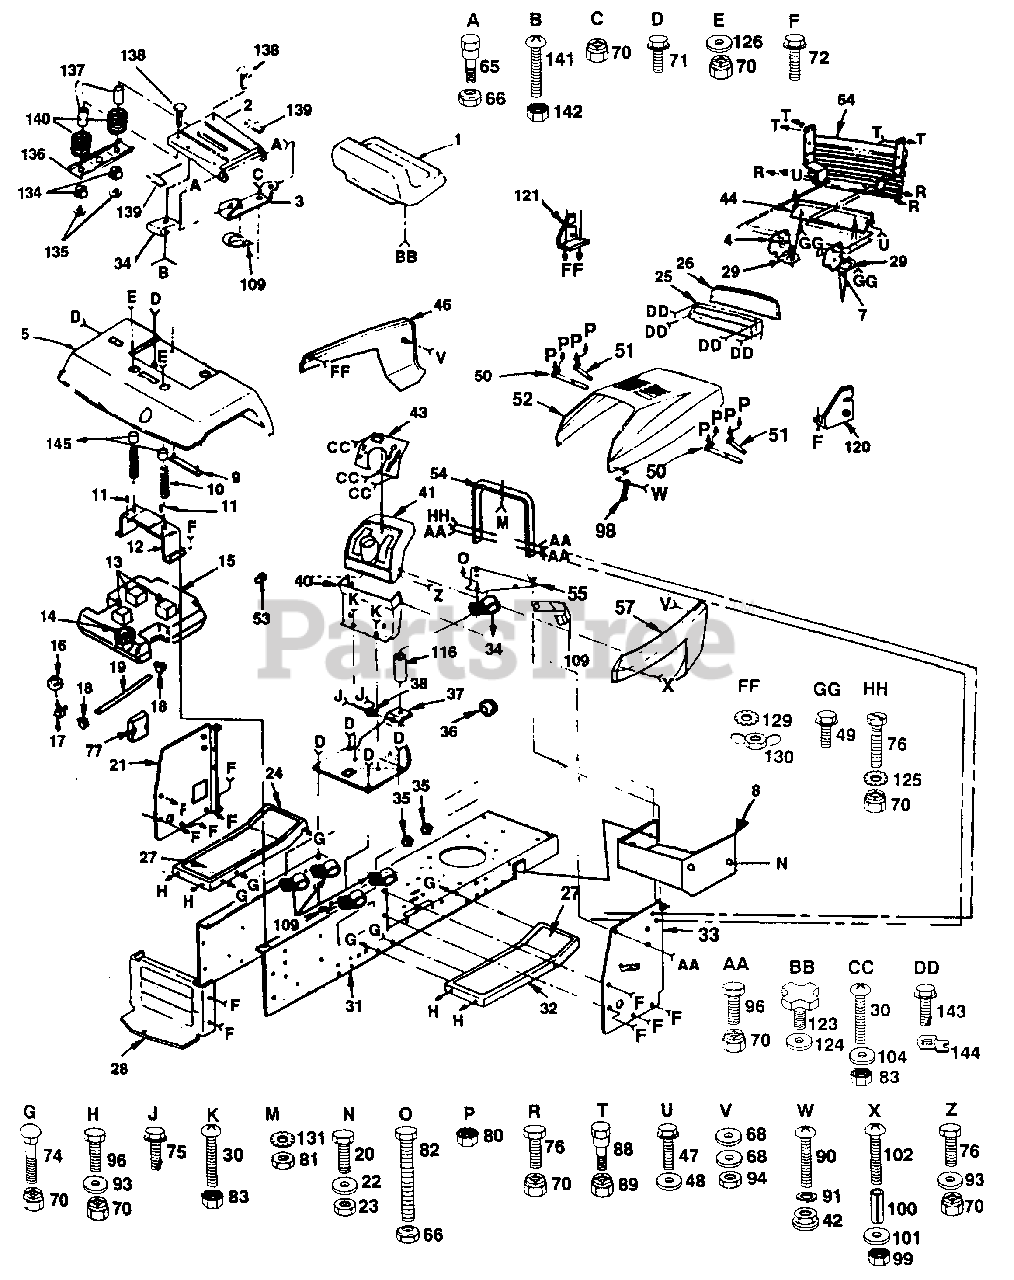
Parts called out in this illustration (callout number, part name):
1	Seat (AYP part number)
2	Pan, Seat (AYP part number)
3	Bracket, Pivot, Seat (AYP part number)
4	Bracket, Asm. L.H. Pivot (AYP part number)
5	Fender (AYP part number)
7	Bracket, Asm. R.H. Pivot (AYP part number)
8	Shield, Heat Front (AYP part number)
9	Strap, Fender (AYP part number)
10	Spring, Compression.Seat (AYP part number)
11	Nut, Push (AYP part number)
12	Bracket, Fender (AYP part number)
13	Pad, Spacer (AYP part number)
14	Cap, Fuel (AYP part number)
15	Tank, Fuel (AYP part number)
16	Bushing (AYP part number)
17	Stem, Tank, Fuel (AYP part number)
18	Clamp, Hose (AYP part number)
19	Line, Fuel (AYP part number)
20	Bolt, Hex Hd. 1/4-20 UNC X 3/4 (AYP part number)
21	Panel, Dash, L.H. (AYP part number)
22	Washer 9/37 X 7/8 X 16 Ga. (AYP part number)
23	Nut, Self Retaining, 1/4-20 (AYP part number)
24	Footrest, L.H. (AYP part number)
25	Bezel, Assembly
26	Lens (AYP part number)
27	Pad, Footrest (AYP part number)
28	Drawbar (AYP part number)
29	Washer, 11/32 X 3/4 X 12 Ga. (AYP part number)
30	Screw, Cr. Thd. 5/16-18 x 3/4 (AYP part number)
31	Chassis (AYP part number)
32	Footrest, R.H. (AYP part number)
33	Panel, Dash, R.H. (AYP part number)
34	Clip, Insulated (AYP part number)
35	Grommet, Split (AYP part number)
36	Grommet (AYP part number)
37	Saddle (AYP part number)
38	Bushing, Steering (AYP part number)
40	Dash Assembly, Lower (AYP part number)
41	Dash (AYP part number)
42	Nut, Weld (AYP part number)
43	Plate, Dash (AYP part number)
44	Strap, Grill (AYP part number)
46	Panel, Side, L.H. (AYP part number)
47	Screw, Hex Wsh. Thd. Cut 1/4-20 X 3/4 (AYP part number)
48	Washer 9/32 X 3/4 X 16 Ga. (AYP part number)
49	Screw, Hex Wsh Thdrol 5/16-18 X 3/4
50	Strap Assembly, Hinge, Rear (AYP part number)
51	Strap Assembly, Hinge, Front (AYP part number)
52	Hood (AYP part number)
53	Plug, Button (AYP part number)
54	Support, Dash (AYP part number)
55	Plate, Support, Battery (AYP part number)
57	Panel, Side R.H. (AYP part number)
64	Grill Assembly (AYP part number)
65	Bolt, Shoulder 5/16-18 (AYP part number)
66	Nut, Lock 5/16-18
68	Washer 9/32 X 3/4 X 16 Ga. (AYP part number)
70	Nut, Crownlock 3/8-16
71	Screw, Hex Washer Thread Rolling 3/8-16 x 1/2 (AYP part number)
72	Screw, Hex Washer Thread Rolling 3/8-16 x 3/4 (AYP part number)
74	Bolt, Carriage 3/8-16 x 3/4 (AYP part number)
75	Screw, Hex Self Tapping #10-16 x 1/2 (AYP part number)
76	Bolt, Hex 3/8-16 x 1 (AYP part number)
77	Cover, Access (AYP part number)
80	Nut, Hex Keps (AYP part number)
81	Nut, Hex 1/4-20 (AYP part number)
82	Bolt, Hex 5/16-18 x 2 (AYP part number)
83	Nut, Keps 5/16-18 (AYP part number)
88	Bolt, Shoulder 1/4-20 (AYP part number)
89	Crownlock Nut 1/4-20 (AYP part number)
90	Screw, Pan Hd. Mach. #10-24 1/2 (AYP part number)
91	Washer, Lock #10 (AYP part number)
93	Washer 13/32 x 13/16 x 12 Ga. (AYP part number)
94	Nut, Fin Hex 1/4-20 UNC (AYP part number)
96	Bolt, Hex 3/8-16 x 3/4 (AYP part number)
98	Latch, Hood (AYP part number)
99	Nut, Keps 10-24 (AYP part number)
100	Spacer, Split 10 x 3/4 (AYP part number)
101	Washer 7/32 x 1/2 x 18 Ga. (AYP part number)
102	Screw, Mach. Cr. Pan 10-24 x 1-1/4 (AYP part number)
104	Washer 11/32 x 11/16 x 16 Ga. (AYP part number)
109	Clip (AYP part number)
116	Spacer (AYP part number)
120	Bracket Assembly, R.H. (AYP part number)
121	Bracket Assembly, L.H. (AYP part number)
123	Adjustment Knob (AYP part number)
124	Washer 17/32 x 1-3/16 x 12 Ga. (AYP part number)
125	Washer Lock 3/8 Ext. Tooth (AYP part number)
126	Washer 13/32 x 1 x 14 Ga. (AYP part number)
129	Washer Lock Ext. Tooth (AYP part number)
130	Wing Nut (AYP part number)
131	Washer, 1/4 Ext. Tooth (AYP part number)
134	Bushing, Snap .80 (AYP part number)
135	Nut, Hex, Large, Flange, Lock (AYP part number)
136	Bracket, Switch Mount (AYP part number)
137	Spacer, Split .28 x .88 (AYP part number)
138	Bolt, Carr. 1/4 x 1-1/4 (AYP part number)
139	Foam Strip (AYP part number)
140	Spring. Compression (AYP part number)
141	Screw, Pan Hd. #10-32 (AYP part number)
142	Nut, Keps #10 (AYP part number)
143	Screw, Hex WH HD Tap #10-16 X 5/8 (AYP part number)
144	"J" Fastener (AYP part number)
145	Spring Cap (AYP part number)
